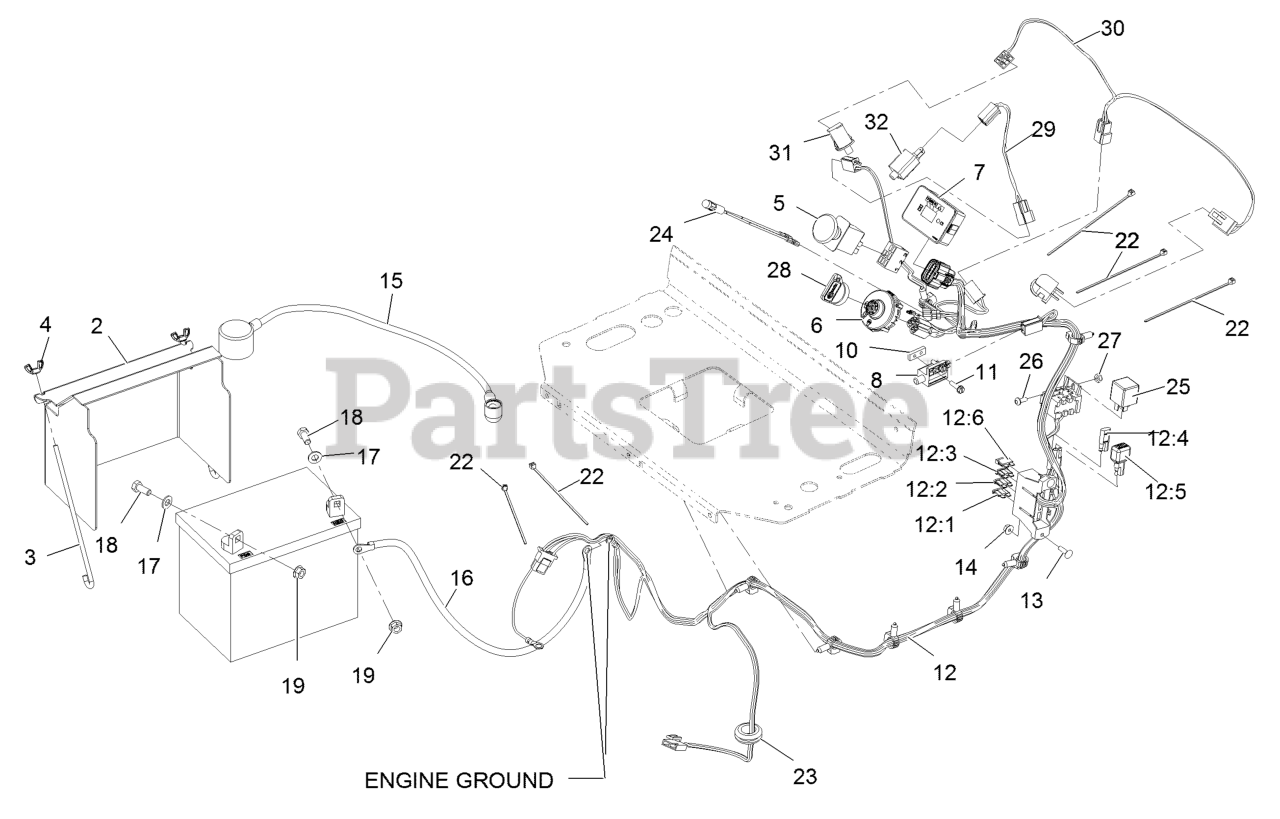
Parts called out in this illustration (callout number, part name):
2	COVER-BATTERY
3	BOLT-HOLDDOWN
4	WINGNUT
5	SWITCH-PTO, ON-ON
7	MODULE-HOUR METER
8	SWITCH-CLOSED, NORMALLY
10	PLATE-TAPPED
11	SCREW-HWH
12	HARNESS-WIRE, EFI
12:1	FUSE-BLADE, 30 AMP
12:2	FUSE-BLADE, 25 AMP
12:3	FUSE-BLADE, 10 AMP
12:6	FUSE-BLADE, 15 AMP
13	SCREW-CARR
15	CABLE-BATTERY, POSITIVE
16	CABLE-BATTERY, BLACK
17	WASHER-PLAIN
18	SCREW-HH
19	NUT-HHF, SMOOTH
22	TIE-CABLE
23	GROMMET
24	INDICATOR-LED, RED
26	SCREW-PPH
27	NUT-LOCK, NI
28	KEY-IGNITION
29	HARNESS-NEUTRAL
30	HARNESS-OPC
31	SWITCH-BAIL
32	SWITCH-OPEN, NORMALLY
